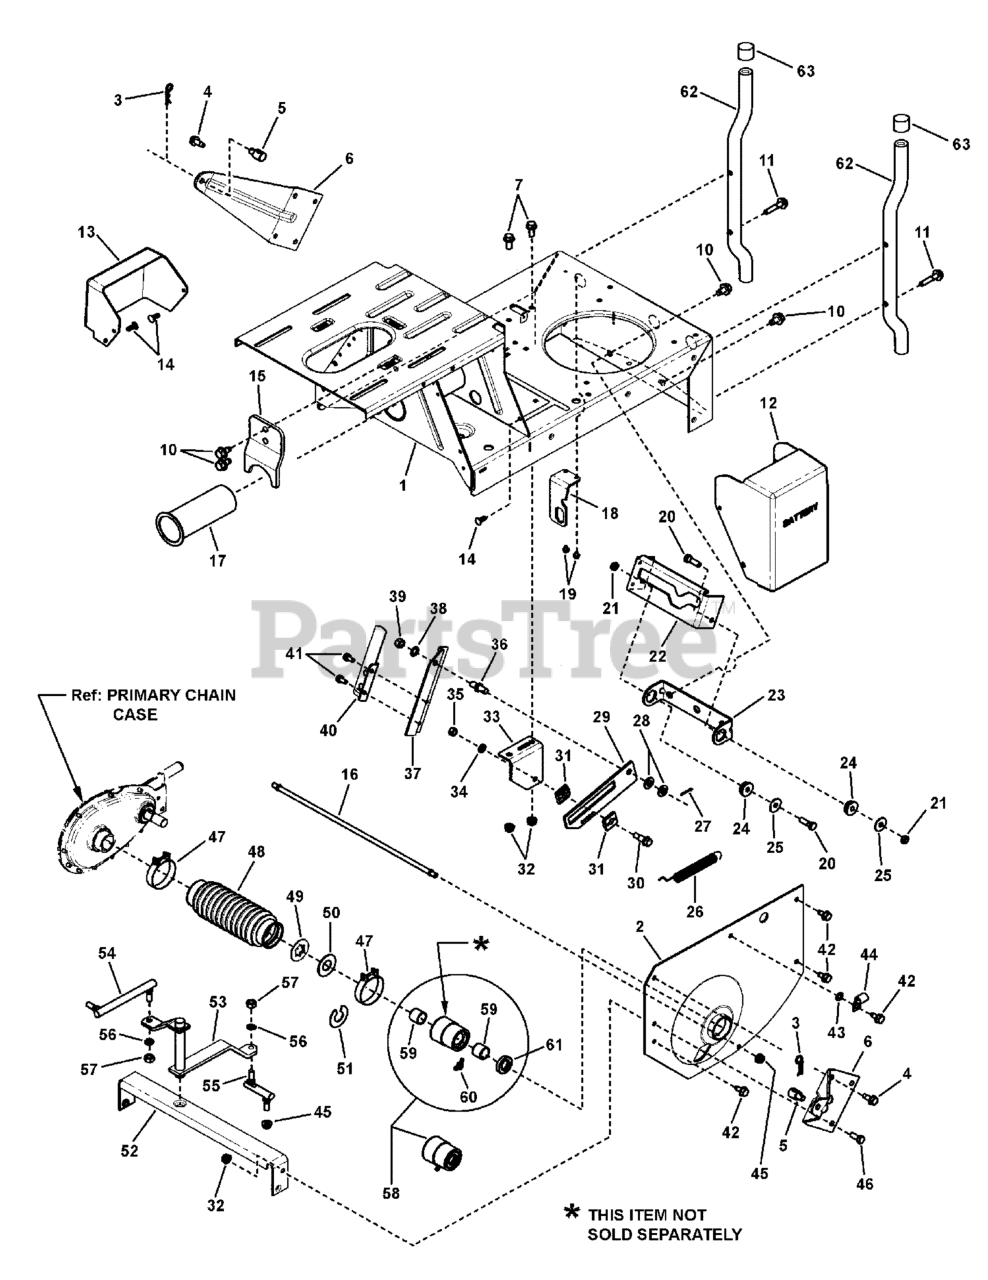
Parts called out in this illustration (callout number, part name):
1	WELDMENT, Main Case
2	FENDER, Left Hand, 1.628" I. D. Hole
3	HAIR PIN, 3/32 x 1-1/2"
4	SCREW, 5/16-18 x 3/4" Hex Washer Self-Tap
5	SWIVEL, Adjustable
6	WING, Rear
7	BOLT, 5/16-18 x 3/4" Hex Flange Lock, GR 5
10	SCREW, 3/8-16 x 5/8" Hex Washer Self-Tap
11	SCREW, 5/16-18 x 1-1/2" Hex Washer Self-Tap
12	COVER, Battery
13	COVER, Solenoid
14	FASTENER, 1/4" Ratchet
15	BRACKET, Belt Adjuster
16	TIE ROD, 5/16-24 thread
17	BUSHING, Pivot
18	BRACKET, Switch
19	SCREW, #10-32 x 1/4" Hex Washer Self-Tap
20	SCREW, 5/16-24 x 1" Hex Head Cap, GR 5
21	NUT, 5/16-24 Hex Center Lock
22	LIFT, Yoke
23	COLLAR, Yoke
24	BEARING, Yoke
25	FENDER WASHER, 5/16"
26	SPRING, Clutch & Brake
27	PIN, 3/32 x 3/4" Cotter
28	WASHER, 3/8" Flat SAE
29	BRACKET, Slide
30	BOLT, 5/16-18 Shoulder
31	SLIDE HALF
32	NUT, 5/16-18 Hex Flange Lock, GR 5
33	BRACKET, Drive Support
34	WASHER, 5/16" Split Lock
35	NUT, 5/16-18 Hex, GR 5 or B
36	STUD, Clutch Link, 3/8-24 thread
37	ARM, Yoke
38	WASHER, 3/8" Internal Tooth Lock
39	NUT, 3/8-24 Hex, GR 5 or B
40	KIT, Leaf Spring Assembly
41	SCREW, 1/4-20 x 1/2" Hex Washer Self-Tap
42	SCREW, 5/16-18 x 5/8" Hex Washer Self-Tap
43	WASHER, 5/16" Internal Tooth Lock
44	CLIP, Wire
45	NUT, 5/16-24 Flange Lock
46	SCREW, 5/16-18 x 3/4" Hex Head Cap, GR 5
47	BOOT CLAMP, 2"
48	BOOT, Rear Axle, Thick Flange
49	WASHER, Thrust
50	THRUST WASHER
51	WASHER, Shim
52	CROSS BRACE
53	WELDMENT, Shift Arm
54	SHIFT LINK, Long (5/16-24 both ends)
55	SHIFT LINK, Short (5/16-24 thread)
56	WASHER, .32 x .58 x .08 Split Lock
57	NUT, 5/16-24 Hex, GR 5
58	ASSEMBLY, DX Bearing
59	BEARING, DX
60	FITTING, Lube, 45 Degree, 3/16" w/Hex (long shank)
61	SEAL, Axle (Dust/Grease)
62	BUMPER, Rear
63	CAP, Bumper
